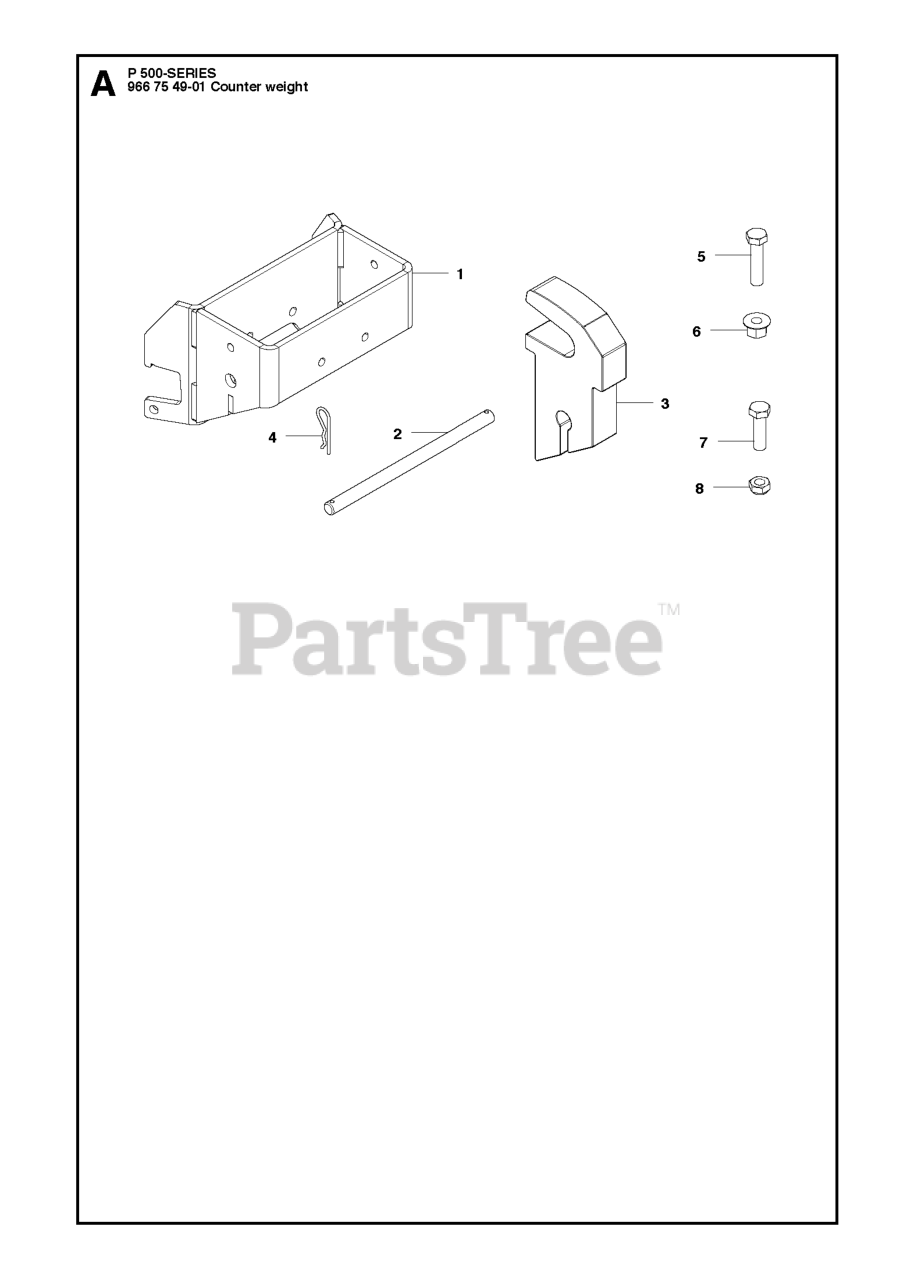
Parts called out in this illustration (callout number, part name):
4	RETAINER
5	Screw
7	SCREW
8	Nut
